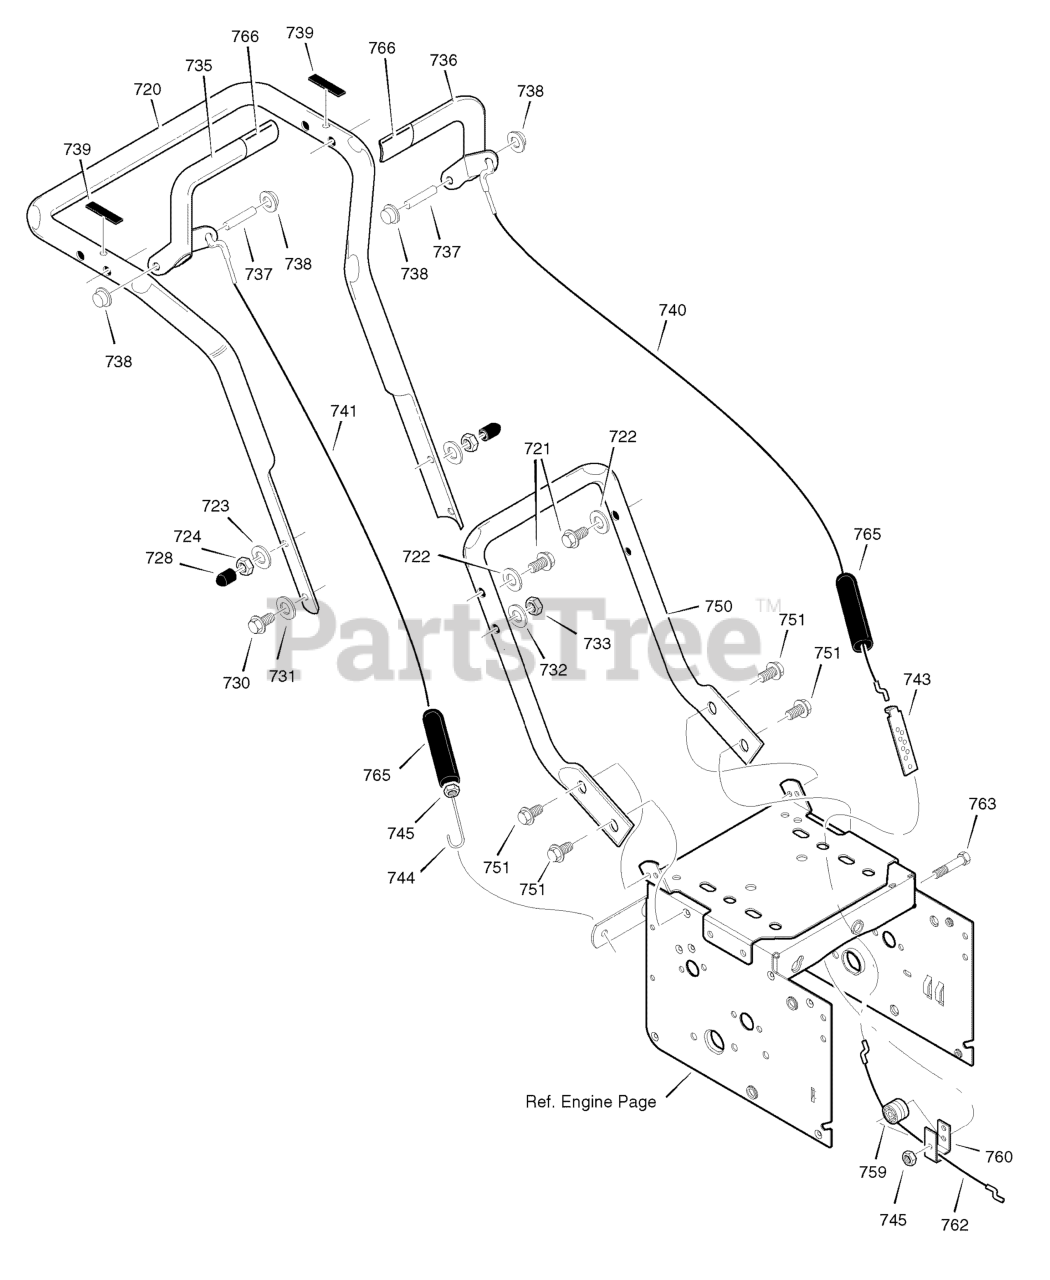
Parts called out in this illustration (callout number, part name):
720	HANDLE, UPPER
721	SCREW, 3/8- 16 X 3
722	WASHER, Flat, 13/32
723	WASHER
724	NUT, 3/8- 16
728	STOP, PLASTIC
730	SCREW, 3/8- 16 X 2
731	WASHER, Flat, 13/32
732	WASHER
733	NUT, 3/8- 16
735	HANDLE, RIGHT
736	HANDLE, LEFT
737	PIN, PIVOT CLUTCH
738	NUT, PUSH ON CAP
739	BUMPER, RECTANGLE
740	CABLE, DRIVE
741	CABLE, AUGER CLUTCH
743	BRACKET, CABLE ADJUSTER
744	SPRING, AUGER CLUTCH
745	NUT, 1/4- 20
750	HANDLE, LOWER
751	SCREW, TAP 5/16-18 X .75
759	SPOOL-CABLE, AUGRT CLUTCH
760	BRACKET, CABLE SPOOL YZ
762	CABLE, LOWER DRIVE 12"
763	BOLT, HEX 1/4-20 X 1.5
765	BOOT, CLUTCH SPRING
